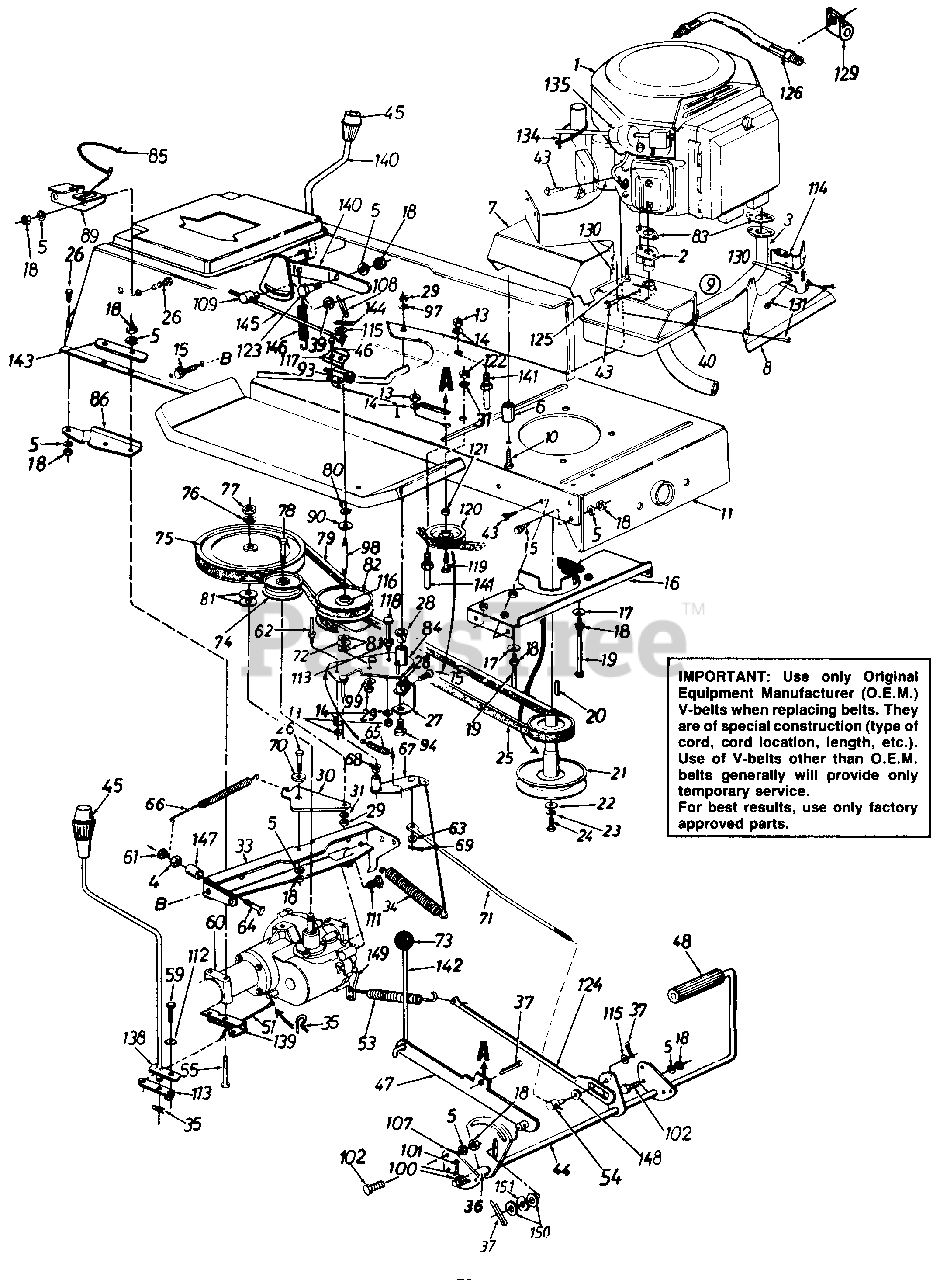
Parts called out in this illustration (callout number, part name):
1	Engine
2	Inlet Tube Ass'y.
3	Formed Tube Ass'y.
4	Hex Nut 5/16-24 Thd.
5	L-Wash. 5/16" I.D.
6	Spacer 1.25" Lg.
7	Muffler Heat Shield
8	Front Heat Shield
9	Muffler Ass'y. Comp.
10	Hex L-Wash. Tap Scr. 3/8-16 Thd
11	Lower Frame Ass'y.
13	Hex Nut 1/4-20 Thd.
14	L-Wash. 1/4" I.D.
15	Hex Wash. TT-Tap Scr. 5/16-18 x.62" Lg.
16	Belt Guard Brkt. Ass'y.
17	Bell-Wash. .345" I.D. x .88"
18	Hex Nut 5/16-18 Thd.
19	Hex Bolt 5/16-18 x 4.0"
20	Sq. Key 1/4" x 1/4" x 2.00"
21	Engine Pulley
22	Fl-Wash. 7/16" I.D. x 1.25"
23	L-Wash. 7/16" I.D.
24	Hex Bolt 7/16-20 x 1.50" Lg.
25	Variable-Speed Belt
26	Hex Bolt 5/16-18 x .75" Lg.
27	Bearing Shaft Bracket Ass'y.
28	Flanged Nyliner Brg. 5/8" I.D. x .88" Lg.
29	Hex Nut 3/8-24 Thd.
30	Idler Bracket
31	L-Wash. 3/8" I.D.
33	Transaxle Support Brkt.
34	Ext. Spring .94" O.D. x 7.58"
35	Inter. Cotter Pin
36	Spacer.63" I.D.
37	Cotter Pin 1/8" Dia. x 1.0" Lg.
39	FL-Wash. .51" I.D. x .75"
40	Exhaust Muffler Sub. Ass'y.
43	Hex Wash. Hd. S-Tap Scr. 1/4-20 x .50" Lg.
44	Clutch/Brake Pedal Ass'y.
46	Truss Mach. B-Tap Scr. #10 x .5" Lg.
47	Parking Brake Lockout Brkt. Ass'y.
48	Foot Pad
51	Shift Lever Rod
53	Ext. Spring 3.6"
54	Ferrule
55	Hex Bolt 5/16-18 x 3.25n
59	Hex Bolt 1/4-28 x .62" Lg.
60	Transaxle Complete
61	Hex L-Nut 1/4-20 Thd.
62	Belt Guard Pin 1/4-20 Thd.
63	Fl-Wash. .34" I.D. x .68" O.D.
64	Hex Wash. TT-Tap Scr. 1/4-20 x 1 .75"
65	Ext. Spring 2.59" Lg.
66	Ext. Spring .5" O.D. x 4.35"
68	Flanged Bearing
69	Cotter Pin 3/32" Dia.
70	Shoulder Spacer .27" Lg.
71	Speed Control Link
72	Truss Bearing .56 Dia. x 1 .25"
74	Fl-ldler Pulley 3.25" x .75"
76	L-Wash. 1/2" I.D.
77	Hex Jam Nut 1/2-20 Thd.
78	Hex Bolt 3/8-24 x 1.75" Lg.
79	Variable Speed Belt
80	Snap Ring .56" Dia.
81	Fl-Wash. .56" I.D. x 1.0" O.D.
82	Variable Speed Pulley Ass'y. 5" O.D.
83	Gasket
90	Teflon Washer .565" I.D.
93	Safety Switch
94	Shld. Bolt 3/8-24 x 3.12" Lg.
97	Bell-Wash. .38" I.D. x .88"
99	Bell-Wash. .39" I.D. x 1.12"
100	Fl-Wash. .64" I.D. x .94"
101	Cotter Pin 3/32" Dia. x 1.0"
102	Hex Wash. Hd. Scr. 5/16-18 x.62" Lg.
109	Ferrule
111	Hex Wash. Tap Scr. 5/16-18 x 1.25" Lg.
112	Bell-Wash. .265" I.D. x .75"
113	Shift Lever Link Ass'y.
114	Front Heat Shield Ext.
115	Fl-Wash. .385" I.D. x .62"
116	Needle Brgs.
117	Switch Plate
118	Hex Bolt 1/4-20 x 3.25" Lg.
119	Hex Bolt 3/8-16 x 1.25" Lg.
120	Fl-ldler w/Flanges 2 75n O.D.
121	Fl-Wash. .39" I.D. x 1.12" O.D.
122	Hex Nut 3/8-16 Thd.
123	Shld. Bolt .437" Dia. x .162"
124	Brake Rod Ass'y.
125	Hex Bolt Washer
130	Speed Nut #10-24 Thd.
131	Hex AB-Tap Scr. #10 x .5" Lg.
134	Cable Tie
138	Shift Lever Ass'y.
139	Shift Lever Support Brkt.
140	Speed Selector Lever Ass'y.
141	Belt Guard Pin
142	Brake Lockout Rod
144	Cotter Pin 1/8" x 3/4" Lg.
145	Speed Selector Rod
146	Ext. Spring 3.97" Lg.
147	Spacer .326" I.D. x .47"
148	Fl-Wash. 518" I.D. x 1.25"
149	Actuating Arm
150	Fl-Wash. .385" I.D. x .87" O.D.
151	Wave Wash. .38" I.D. x .75"
